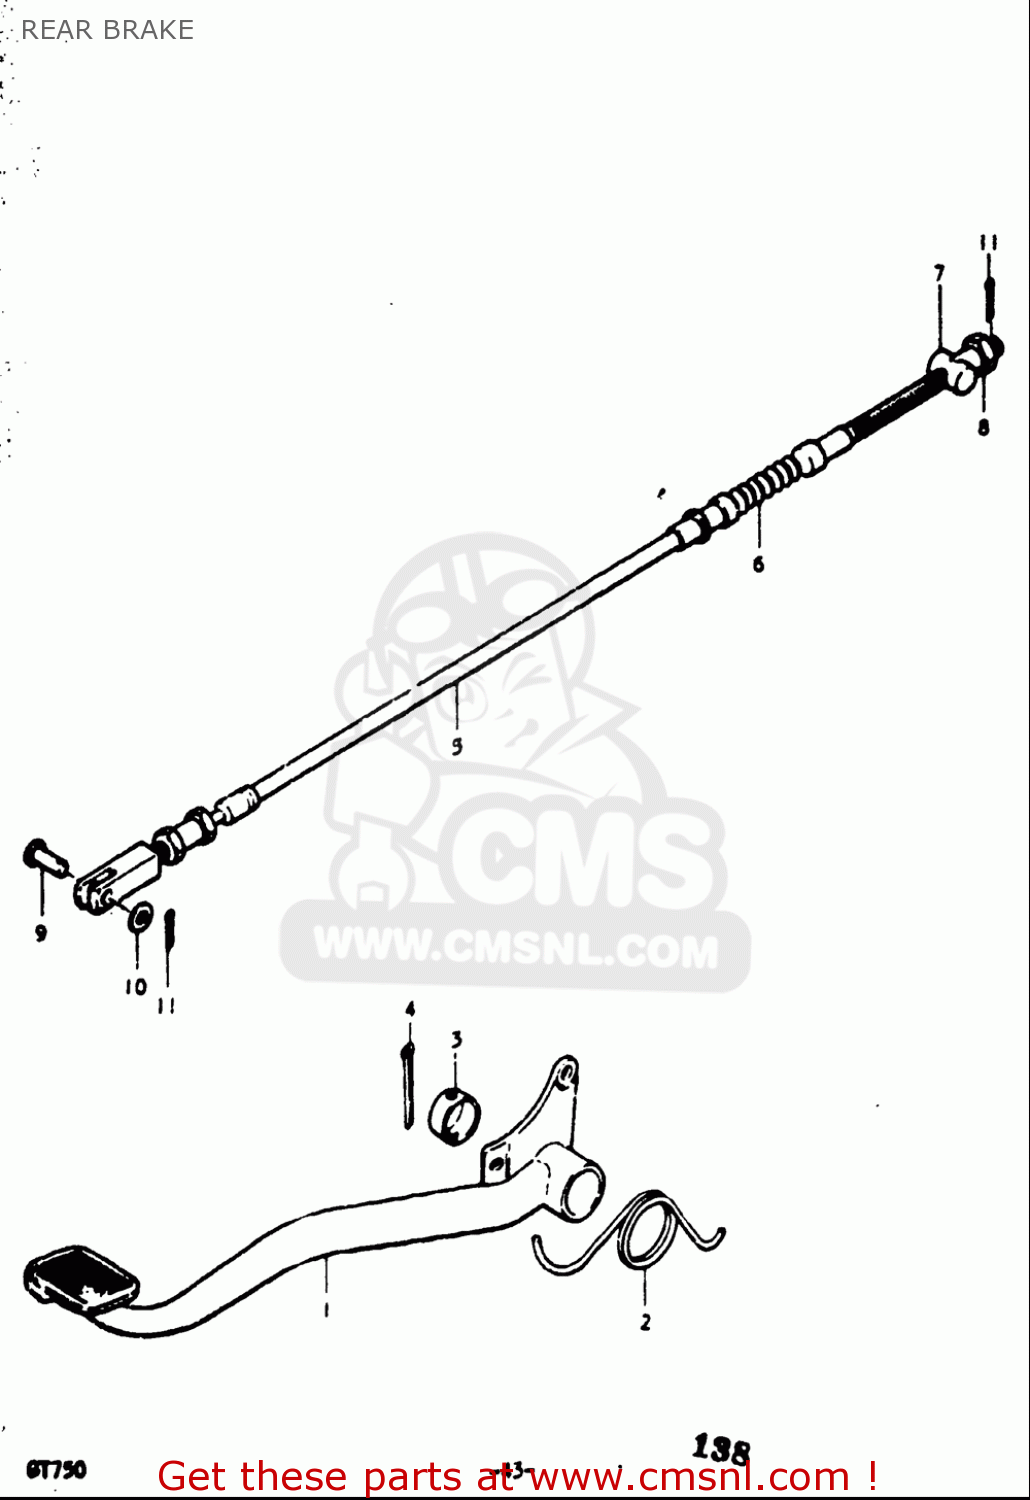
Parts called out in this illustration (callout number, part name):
2	SPRING
4	PIN, COTTER
5	CABLE ASSY,RR BRAKE
6	SEAL,DUST
7	PIN(13X18)
8	NUT
9	PIN(L:17.5)
10	WASHER
11	PIN
